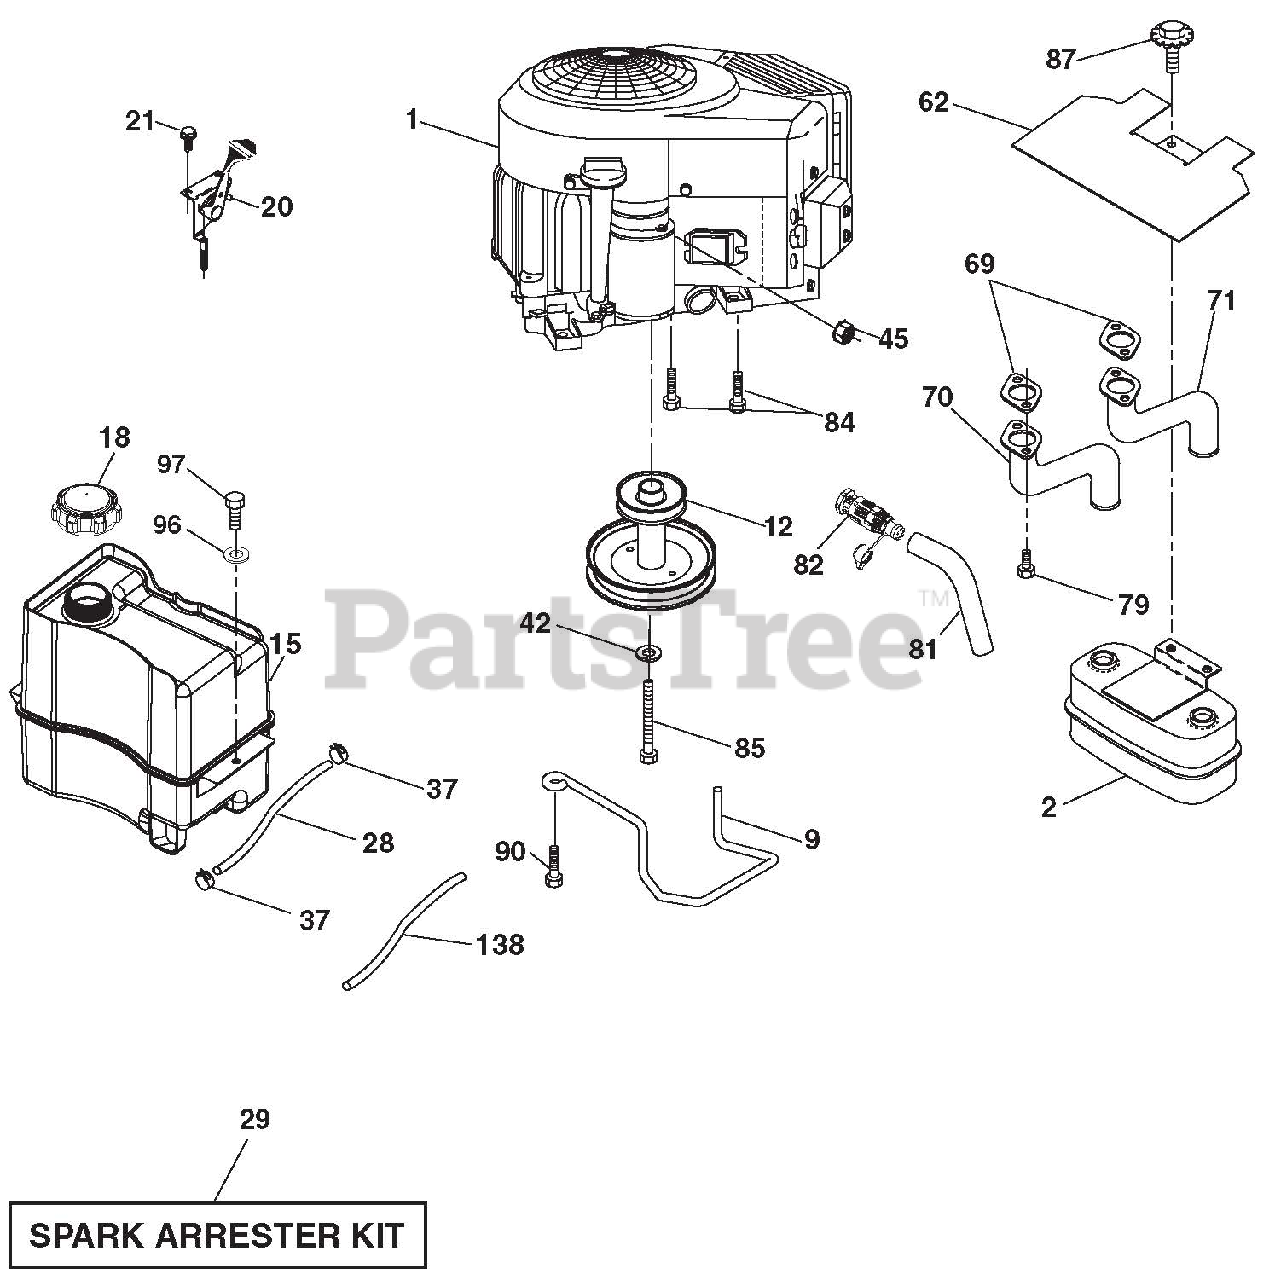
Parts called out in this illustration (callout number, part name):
1	ENGINE BRIGGS
2	MUFFLER ASM.
9	KEEPER.BELT
12	PULLEY.ENGINE.5.0.P.D.
15	TANK.FUEL.2.5.GAL.
18	CAP.FUEL
20	CONTROL THROTTLE/CHOKE
28	LINE.FUEL.20"
29	KIT.SPARK ARRESTOR(392390 B&S)
37	CLAMP.HOSE.BLK.
42	WASHER.LOCK.HVY HLCL.SPR.7/16
45	Nut, Keps Hex 1/4-20 unc
62	SHIELD.HEAT.MUFFLER.
69	GASKET MUFFLER
70	EXHAUST TUBE LH
71	EXHAUST TUBE RH
79	SCREW SOCKET HEAD 5/16-18 X 1
81	TUBE.DRAIN.OIL.EASY
82	VALVE OIL DRAIN
84	Screw 3/8-16 x <
85	BOLT.HEX.7/16-20X4XGR5-1.5THR.
87	BOLT.5/16-18 UNC X 1 W/SEMS.BL
90	SCREW.3/8-16X1.SMGML.TAP/R.BLK
96	WASHER.9/32 X 7/8 X 16GA.
97	SCREW.HEXWSH.THDROL.1/4-20X3/4
138	PURGE.LINE.CARB
